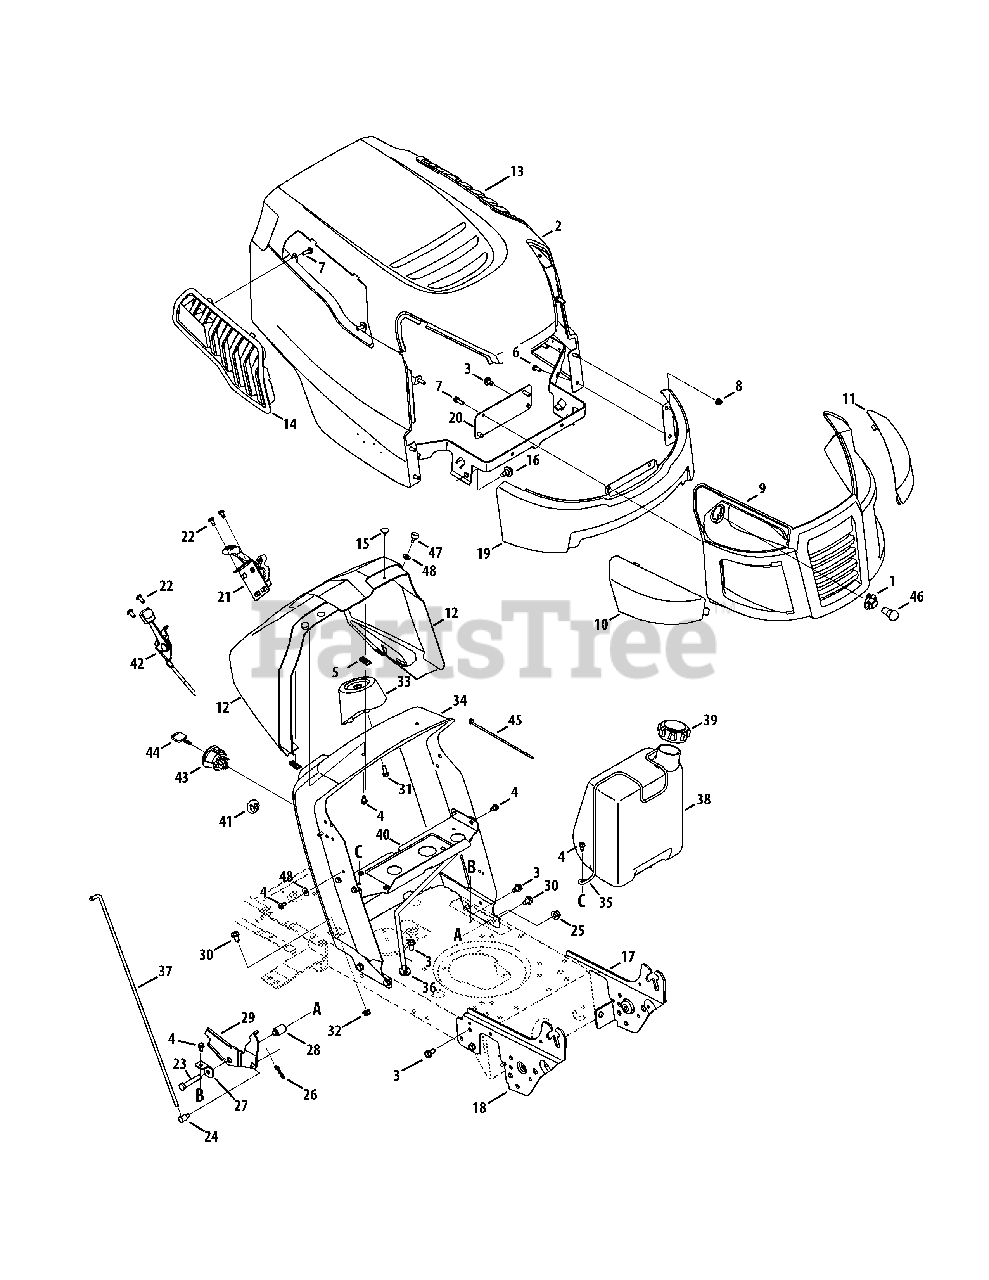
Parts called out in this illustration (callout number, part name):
1	Bulb Socket
2	Hood Assembly
3	Screw, 5/16-18 x .750
4	Hex Washer Screw, 1/4-20 x .500
5	Tin Clip Nut, 1/4-20
6	Hex Screw, 1/4-20 x .620
7	Screw, 1/4 x .750
8	Nut, Hex Flange Insert Lock, 1/4-20
10	Headlight Lens, RH
11	Headlight Lens, LH
12	Dash Collar
13	Hood Scoop, LH
14	Hood Scoop, RH
15	Bumper
16	Shoulder Screw, 5/16-18
17	Left Support Pivot Bracket
18	Right Support Pivot Bracket
19	Lower Grill
20	Lower Grill Bracket
21	Speed Selector
22	Self-Tap Screw, 1/4-20
23	Hex Head Screw, 3/8-16
24	Ferrule, 1/4-20 x 1.00
25	Nut, Hex Flange Insert Lock, 3/8-16
26	Cotter Pin
27	Speed Latch Support Tab
28	Flange Spacer
29	Speed latch
30	Self-Tap Screw, 5/16-18
31	Hex Screw, 1/4 x .750
32	Nut, Hex Flange Lock, 5/16-18
33	Steering Support
35	Fuel Tank Support Rod
36	Dash support Rod
37	Speed Selector Control Rod
38	1.5 Gallon Fuel Tank
39	Fuel Cap
40	Gas Tank Support Bracket
41	Choke Plug
42	Throttle/Choke Assembly
43	Key Switch Module
44	Key (2 pack)
45	Cable Tie
46	Headlight Bulb
47	Ratchet Clip: .250 x .500
48	Flat Washer, .25 x .630 x .0515
